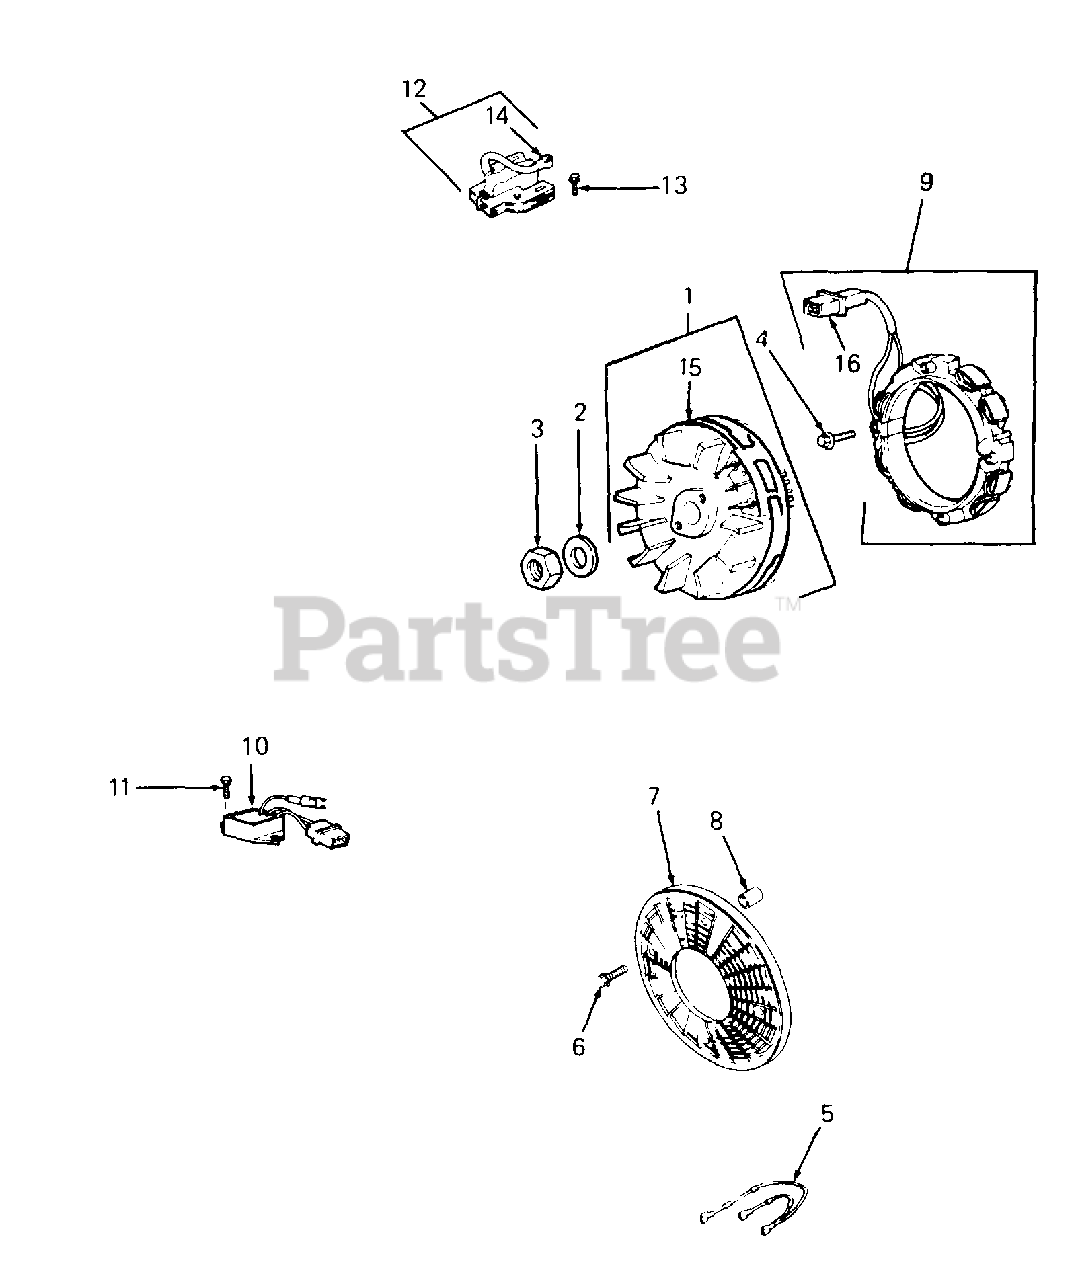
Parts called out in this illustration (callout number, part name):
1	Flywheel & Ring Gear
2	Washer, Spring
4	Screw, Mounting
5	Wire, Ground
6	Screw, Sems
7	Screen, Rotating
8	Spacer
9	Stator, 16 Amp
10	Regulator
11	Screw, Mounting
12	Armature
13	Screw, Mounting
15	Gear, Flywheel Ring
16	Diode, Connector Assy
